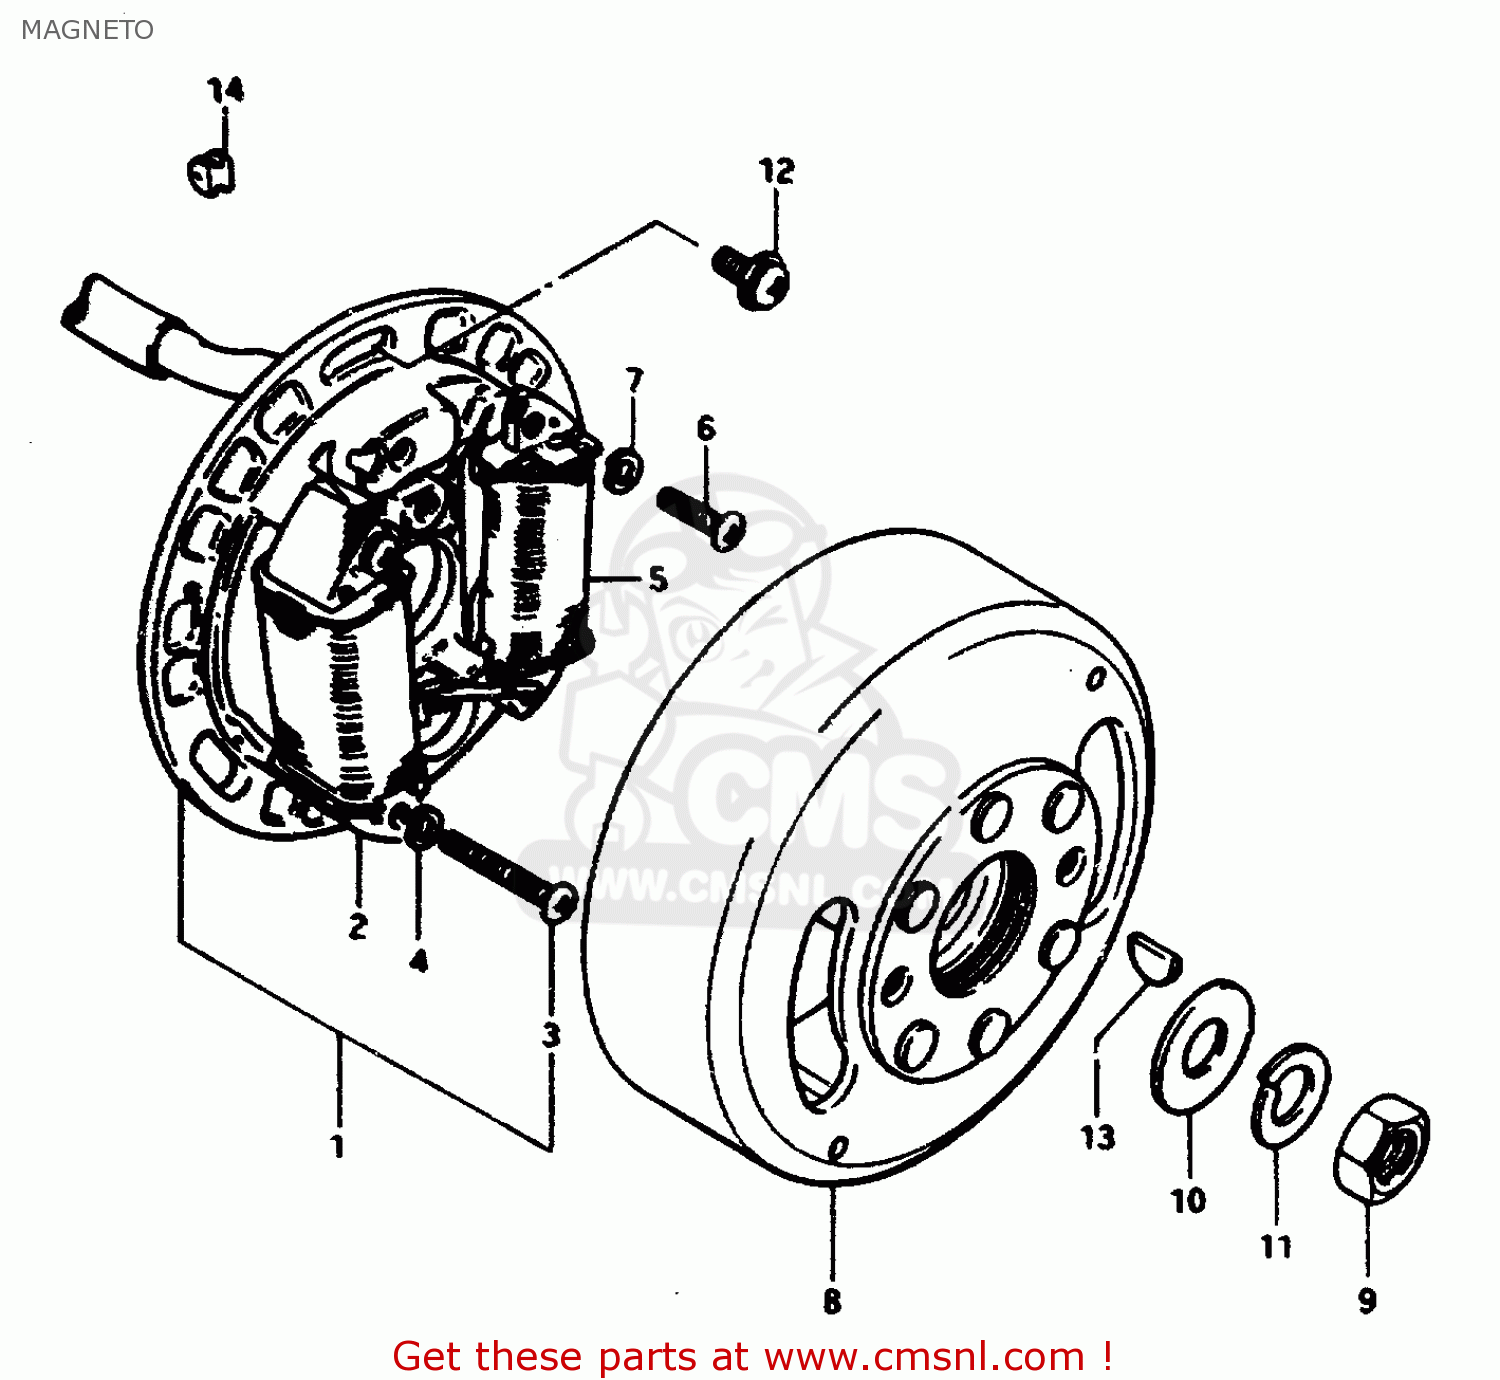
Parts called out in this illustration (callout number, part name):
1	STATOR ASSY
2	COIL,LIGHTING
3	SCREW (4X30)
4	LOCK WASHER
5	COIL,PRIMARY
6	SCREW
7	LOCK WASHER
8	ROTOR ASSY
9	NUT (10MM)
10	WASHER
11	LOCK WASHER
12	SCREW(5X14)
13	KEY
14	GROMMET,NEUTRAL LEAD WIRE
